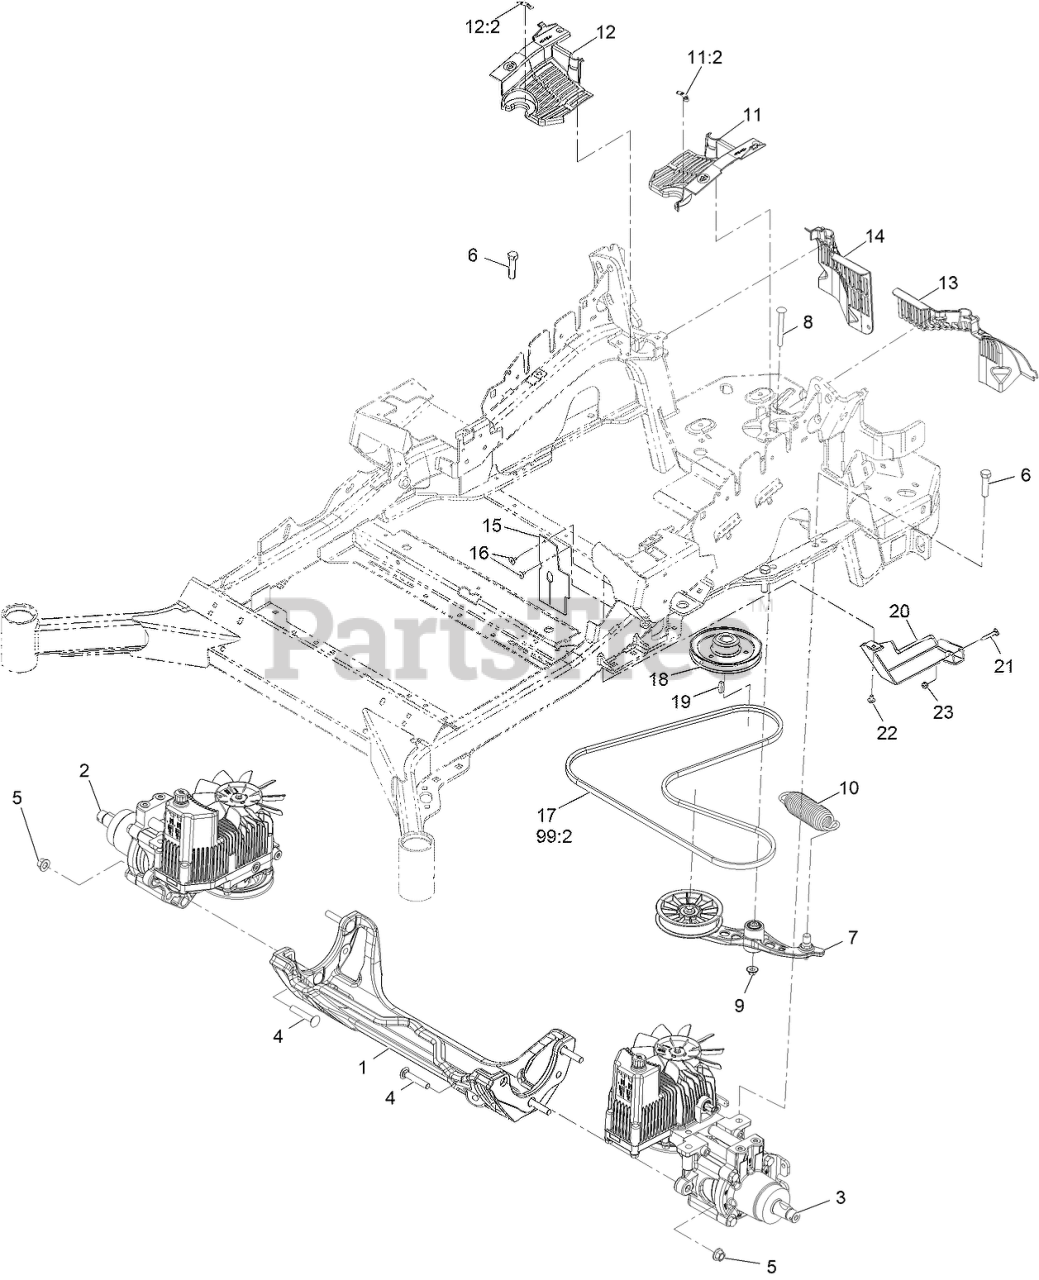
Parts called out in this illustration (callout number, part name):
1	CRADLE-HYDRO
2	Hydro-RH
3	Hydro-LH
4	SCREW-CARR
5	Nut-Lock 1/2-13
6	SCREW-HH
7	PUMP IDLER ASM
8	BOLT-SHOULDER, CARRIAGE 3/8-16 X 3 1/2
9	Nut-Nyloc 3/8-16 Flg
10	SPRING-EXTENSION
11	LH HYDRO GUARD ASM
11:2	DECAL-OIL, HYDRO
12	RH HYDRO GUARD ASM
12:2	DECAL-OIL, HYDRO
13	GUARD-HYDRO REAR, LH TRIM
14	GUARD-HYDRO, REAR (RH)
15	DEFLECTOR-AIR FLOW
16	RIVET-POP
18	SHEAVE, W/HUB
20	TANK GUARD WLDMNT
21	SCREW-CARR
22	SCREW AND WASHER ASM
